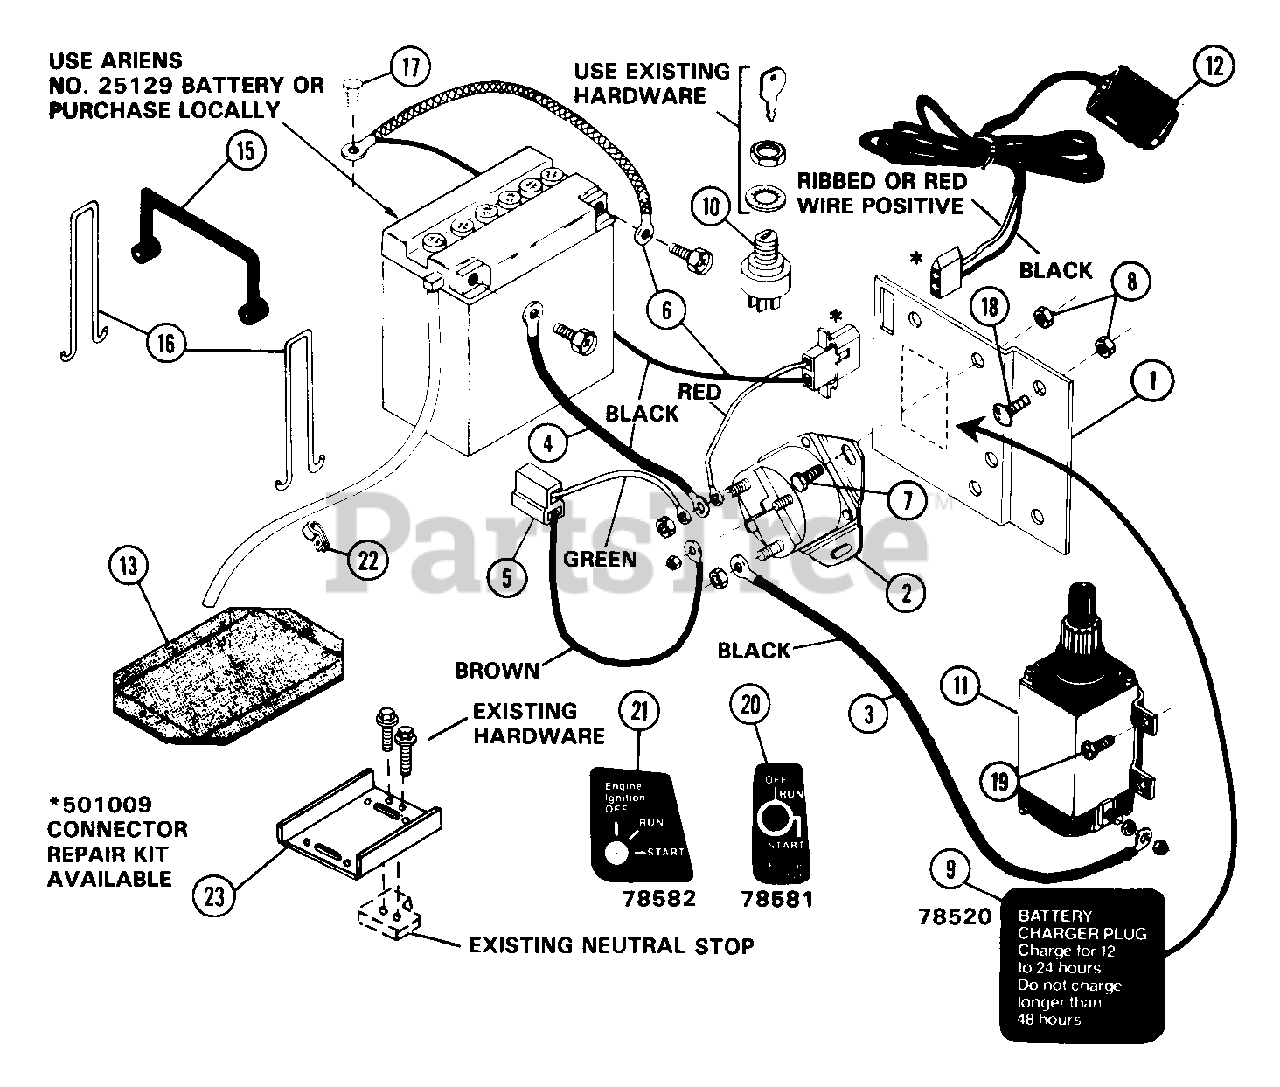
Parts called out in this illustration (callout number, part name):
1	BRACKET SOLENOID
2	SOLENOID,STARTER SWITCH
3	GROUND CABLE
4	GROUND CABLE .25X13.00X.31
5	WIRING HARNESS SWITCH
6	WIRING HARNESS BATTERY CHARGER
7	BLT-HEX .25-20X.50 PL GR2
8	NUT-LK-CTR .250-20 PL
9	CHARGING DECAL
10	KEY SWITCH
11	STARTER MOTOR, TECUMSEH
12	BATTERY CHARGER
13	RUBBER PAD
15	BATTERY STRAP
16	HOOK
17	SCR-TAP 10-24X.375 CRPH 1A
18	BLT-RDHDSQNK .25-20X.62 PL
19	SCR-CAP CR SEMS .25-20X.50 PL
20	ELECTRIC START DECAL
21	ENGINE IGNITION DECAL
23	BATTERY TRAY
